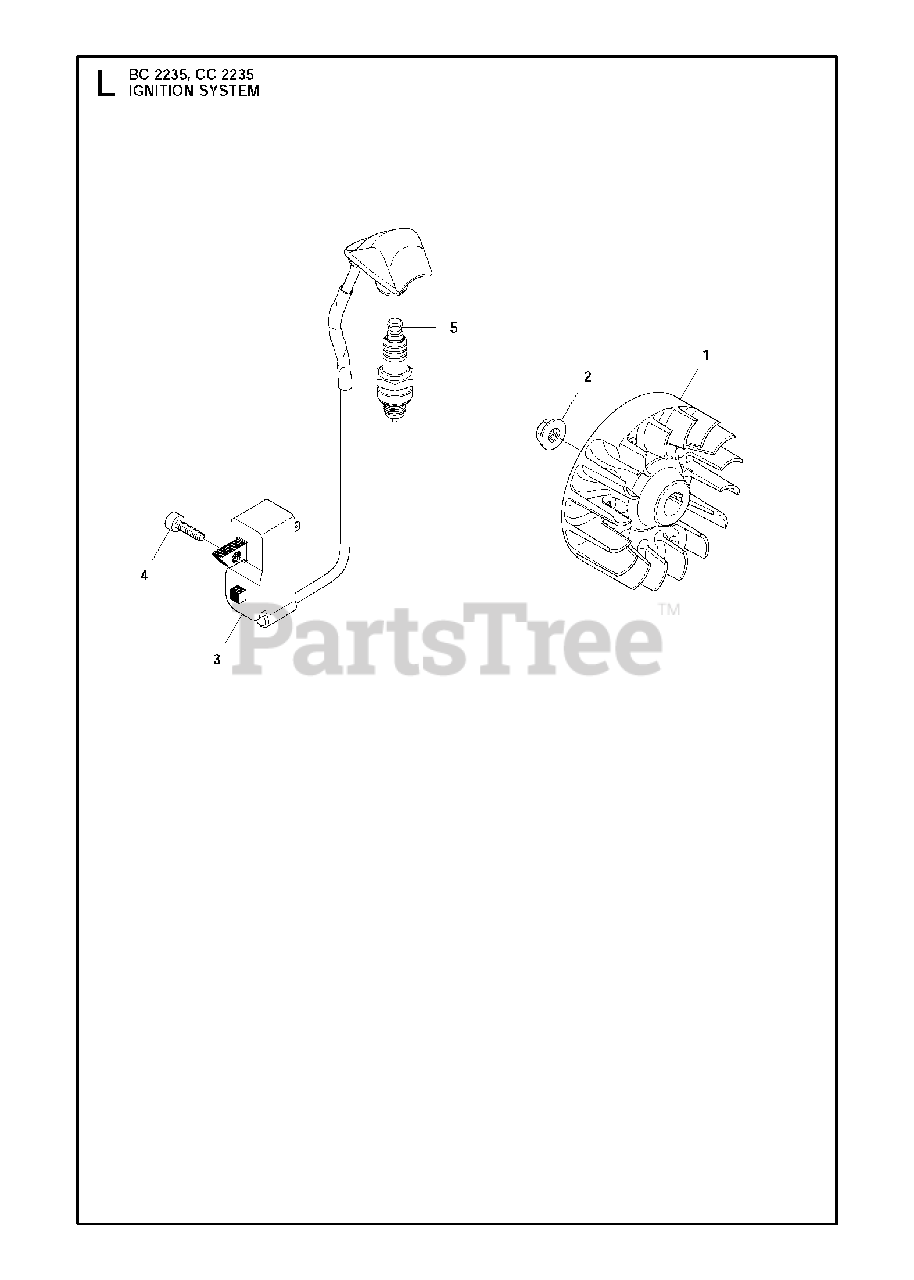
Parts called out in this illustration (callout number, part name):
1	FLYWHEEL
2	FLANGE NUT
3	IGNITION MODULE OPS
5	SPARK PLUG RCJ6Y NLA
